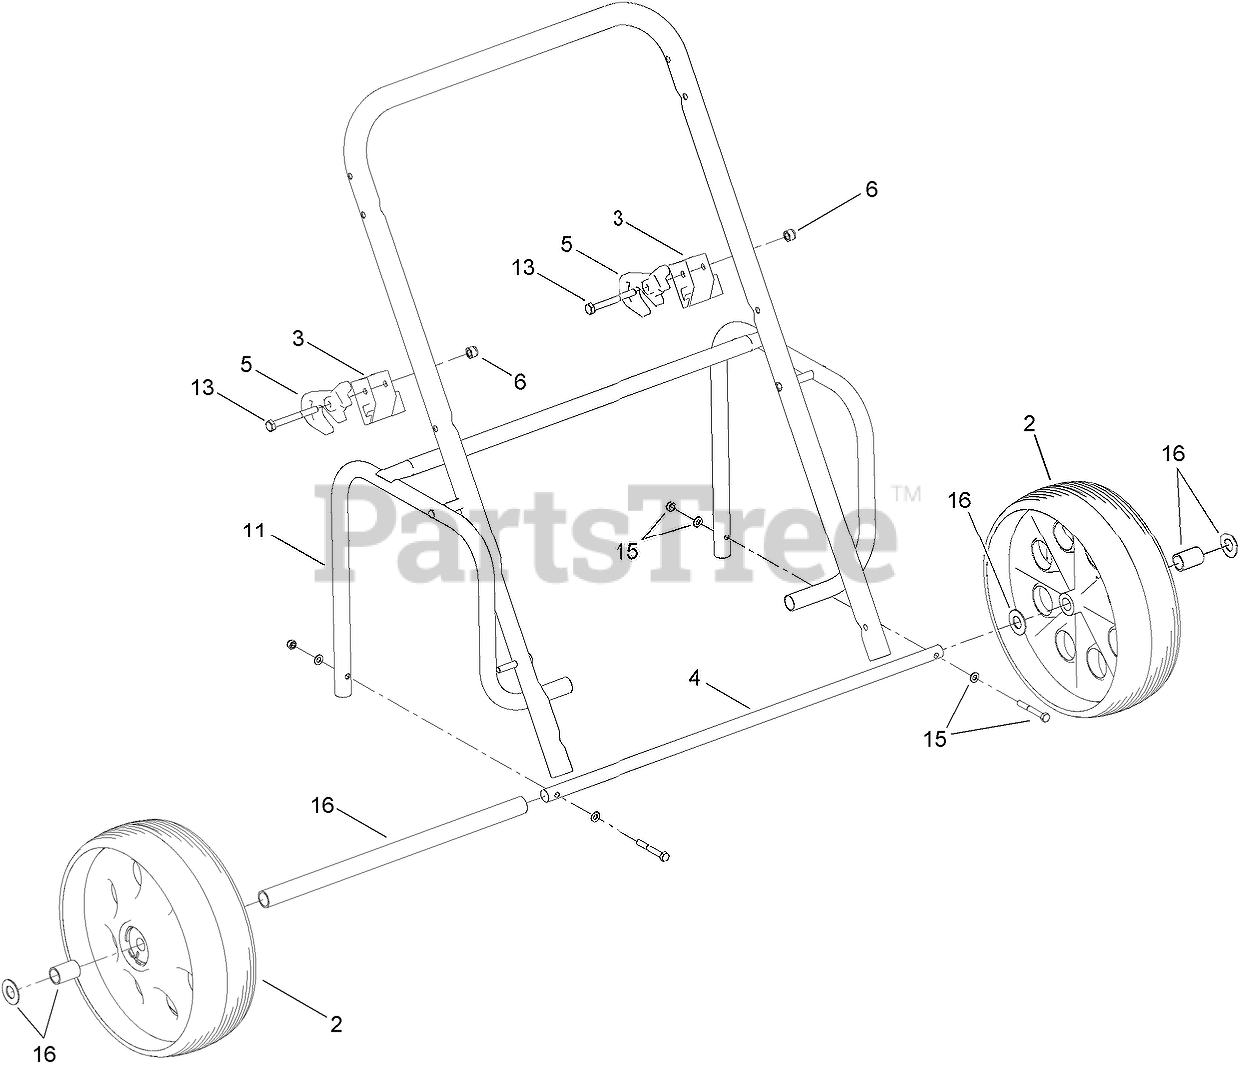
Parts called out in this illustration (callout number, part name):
2	WHEEL
3	SPACER
6	NUT-NYLOC
11	UNDERCARRIAGE
13	BOLT-HEX
15	AXLE BOLTS AND NUTS KIT
16	AXLE SPACER KIT
